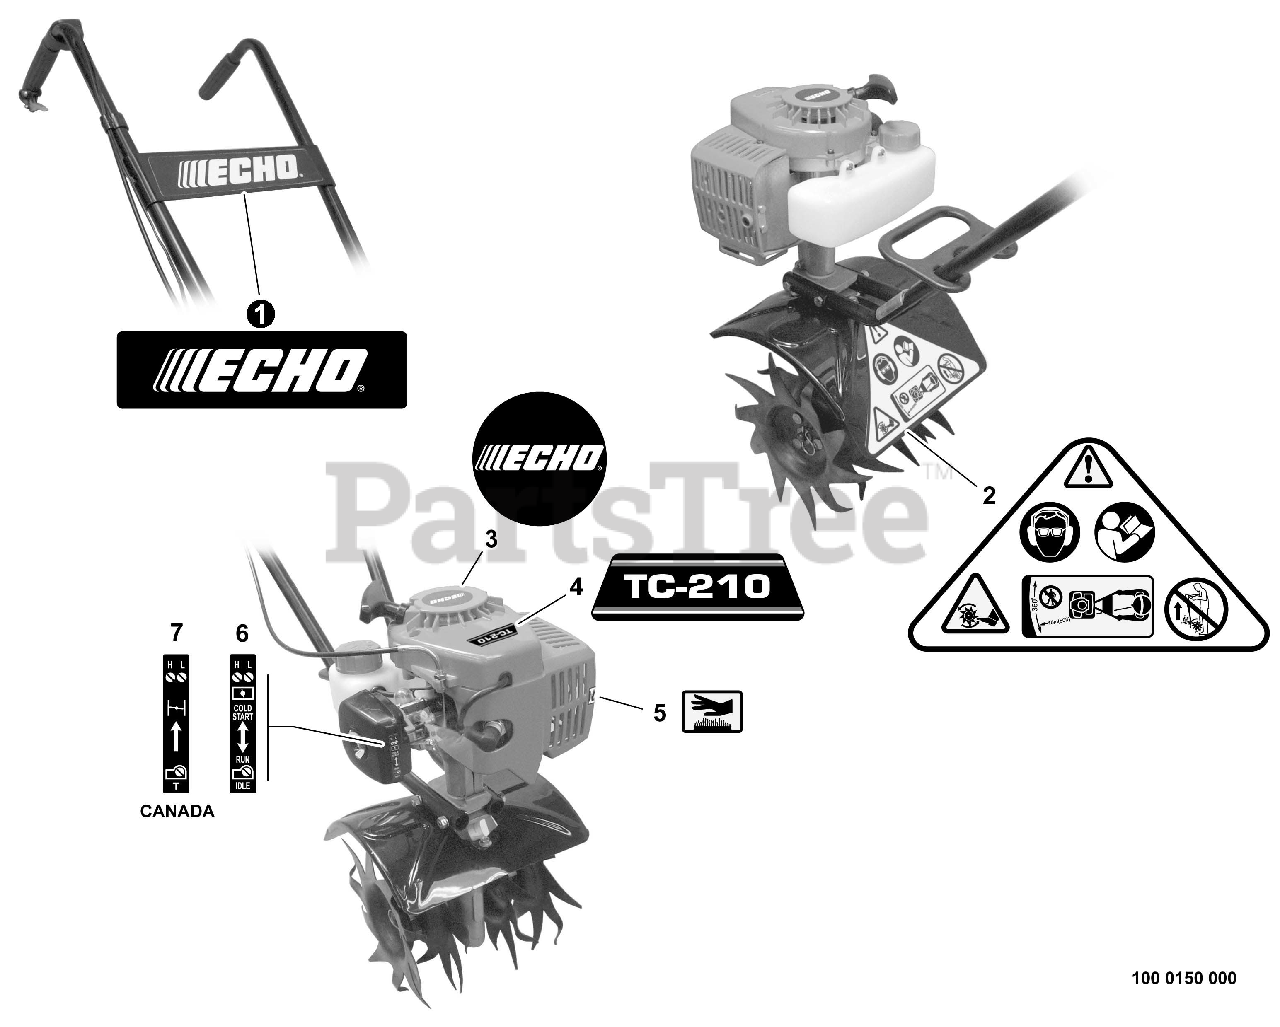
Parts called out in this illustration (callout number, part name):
1	LABEL - ECHO
2	LABEL - CAUTION
3	LABEL - ECHO
4	LABEL - MODEL TC-210
5	LABEL - HOT SURFACE
6	LABEL - CHOKE
7	LABEL - CHOKE
